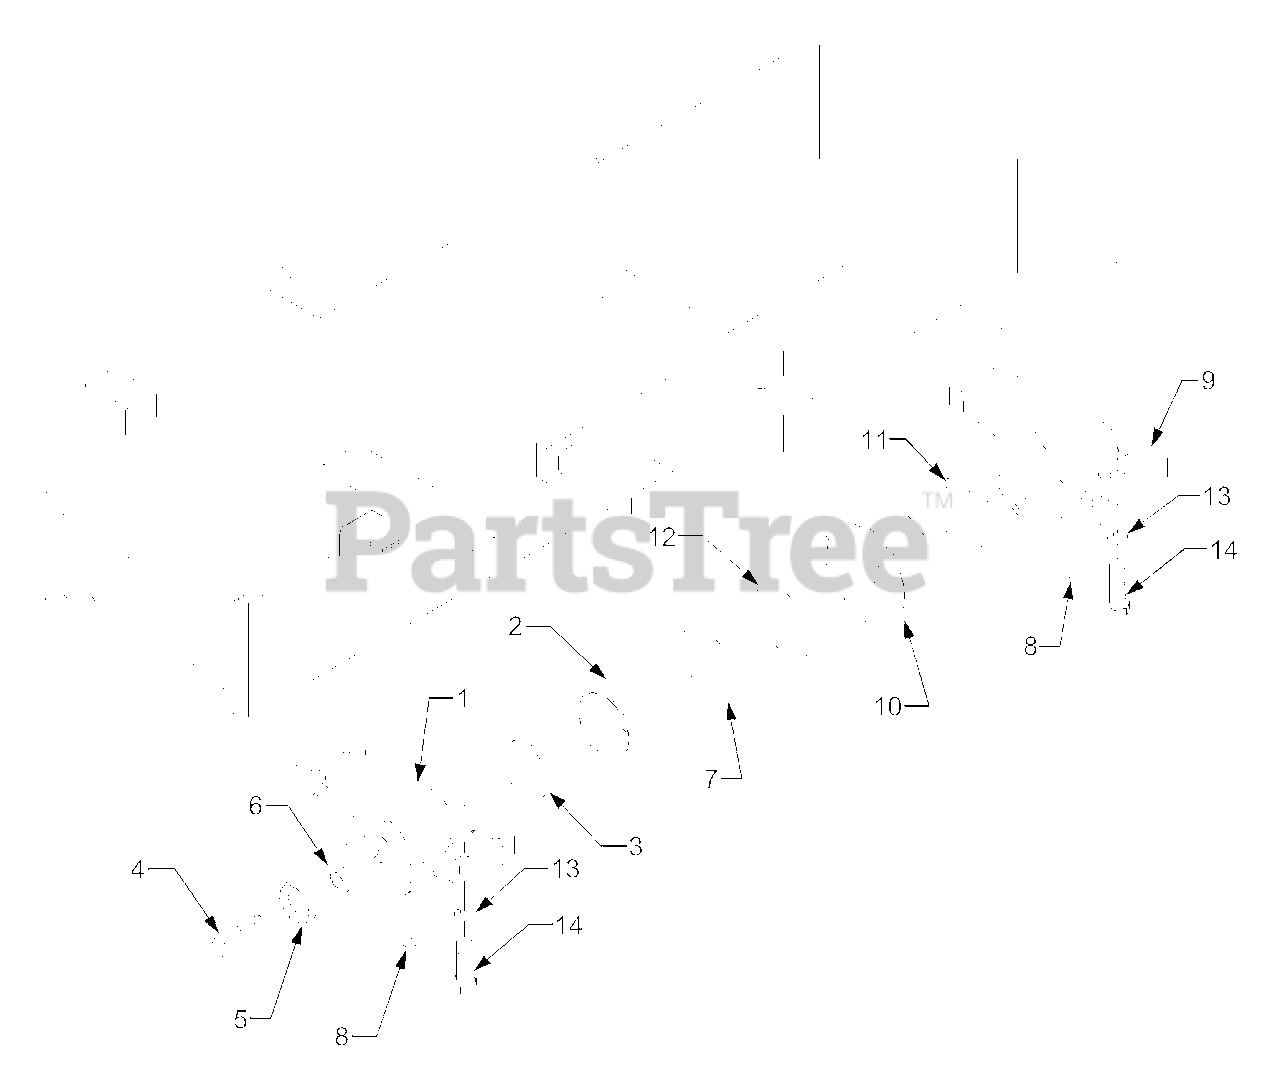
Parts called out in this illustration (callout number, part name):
1	Bracket, Front
8	Nipple, Grease
9	Bracket, Rear
11	Collar, Thrust
14	Washer, Spring
